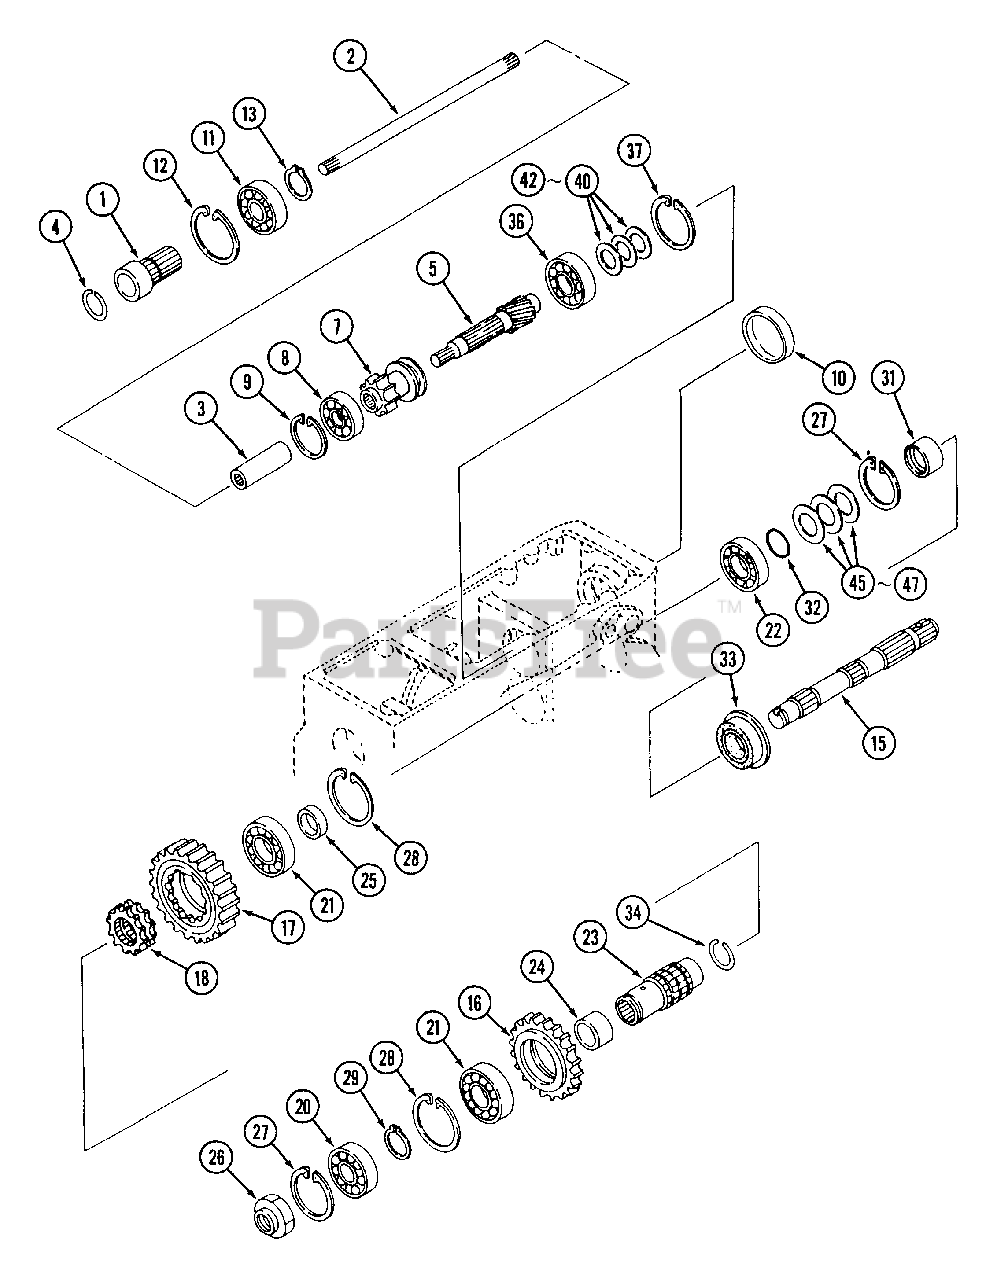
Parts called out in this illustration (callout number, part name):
3	Collar
7	Gear, 19T
15	Shaft, PTO Drive
29	Ring
33	Seal, Oil
40	Liner t=0.2
42	Liner t=0.8
45	Liner t=0.15
47	Liner t=0.8
